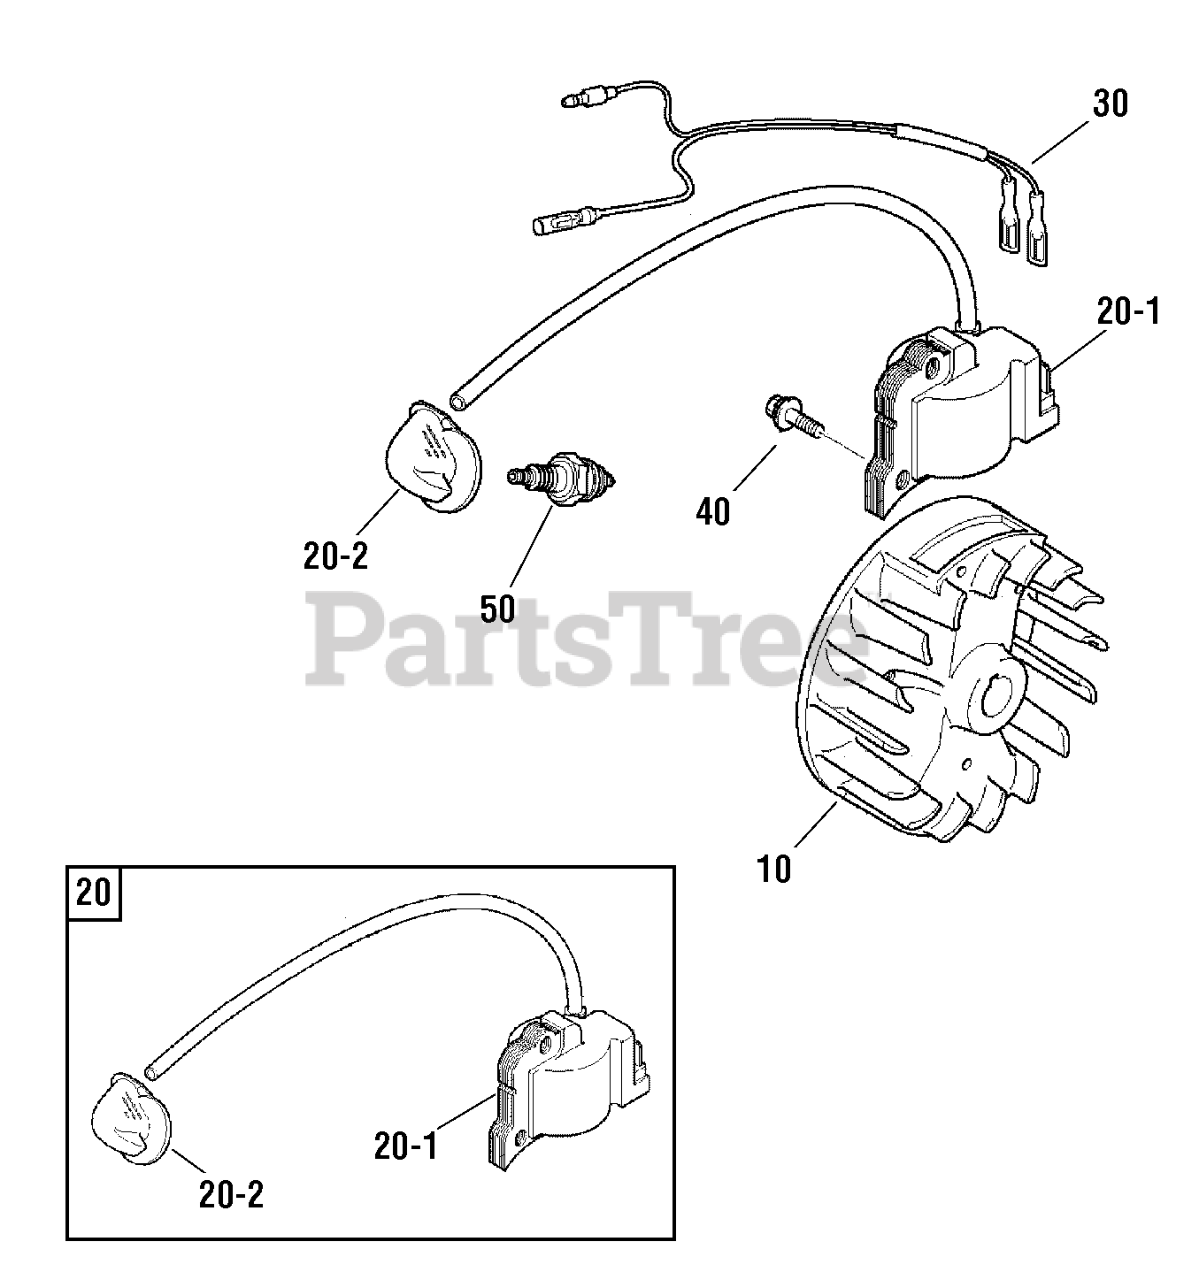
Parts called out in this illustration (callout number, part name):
20	COIL ASSEMBLY
20-1	COIL, Ignition
20-2	CAP, Plug
30	WIRE, Lead
40	BOLT & WASHER
